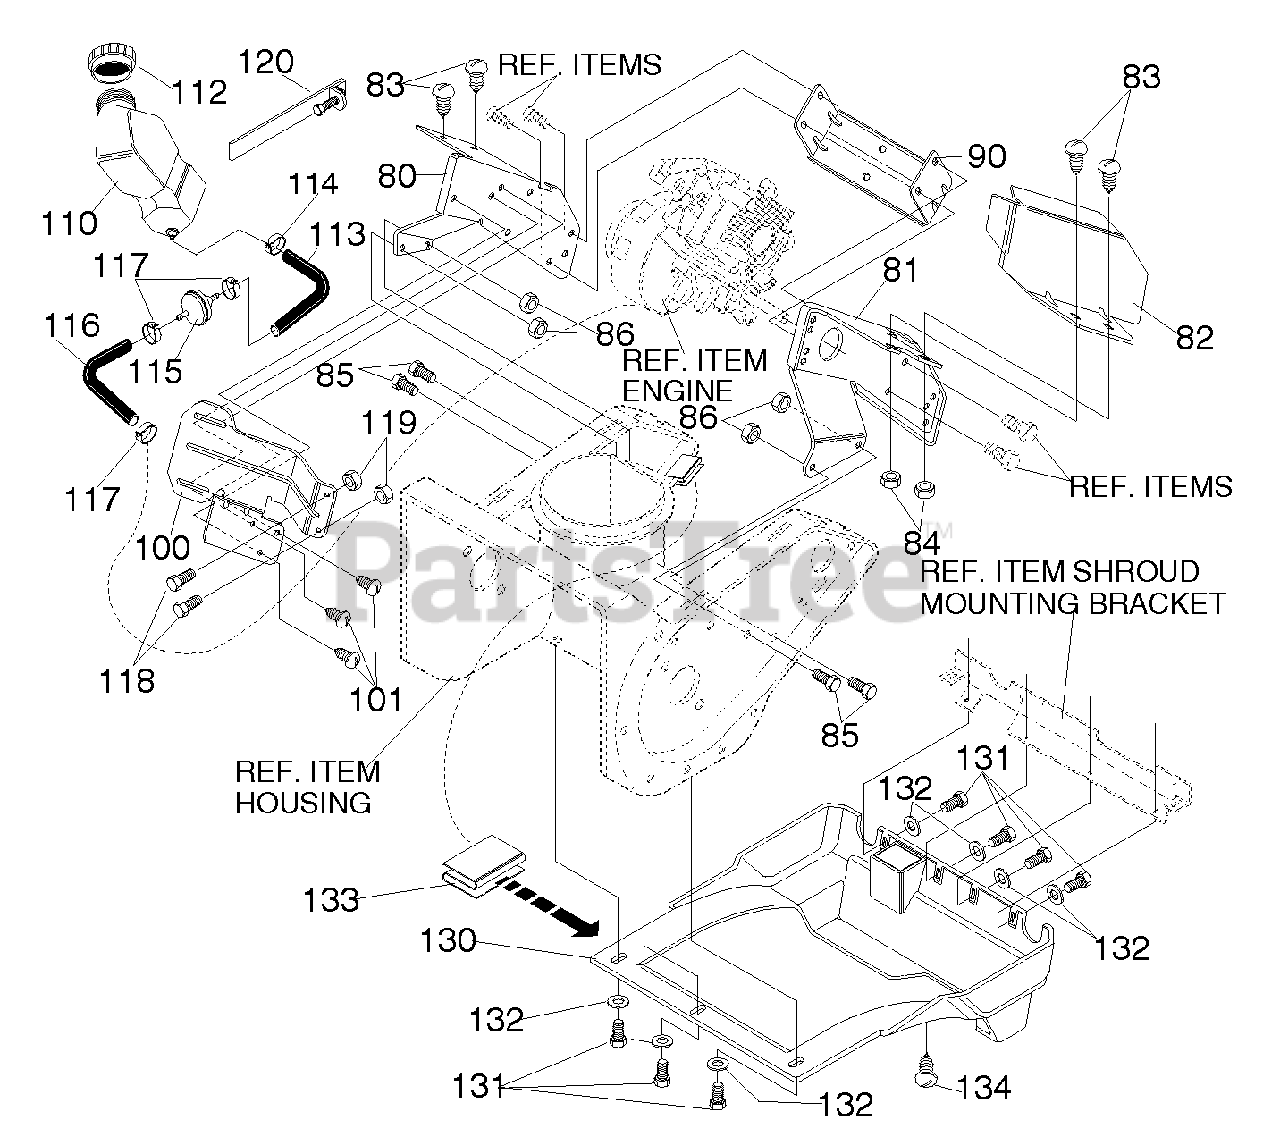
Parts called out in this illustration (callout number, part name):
80	PLATE, REAR MT. RH
81	PLATE, REAR MT. LH
82	SHIELD, ENGINE HEAT
83	SCREW 1/4-20 X .63
84	NUT, 1/4-20 MACK LOCK
85	SCREW 5/16-18 X .50
86	NUT, 5/16-18 RGHXCTRLK
90	SUPPORT, FRAME ENG MT
100	BRACKET, GAS TANK
101	SCREW, #10-24 X .63
110	TANK, FUEL
113	TUBING 8 INCHES
114	CLAMP, HOSE SCREW TYP
115	FILTER, IN LINE
116	TUBING, 3 INCHES
117	CLAMP, HOSE
118	SCREW 10-24 X .50
119	NUT, #10-24 REGHXCTRLK
120	CLAMP, WORM
130	SHROUD, BOTTOM
131	SCREW #10-24 X .63 TAP
132	FLATWASHER
133	CLIP, "S" TINNERMAN
134	SCREW, 10-16 X .50
